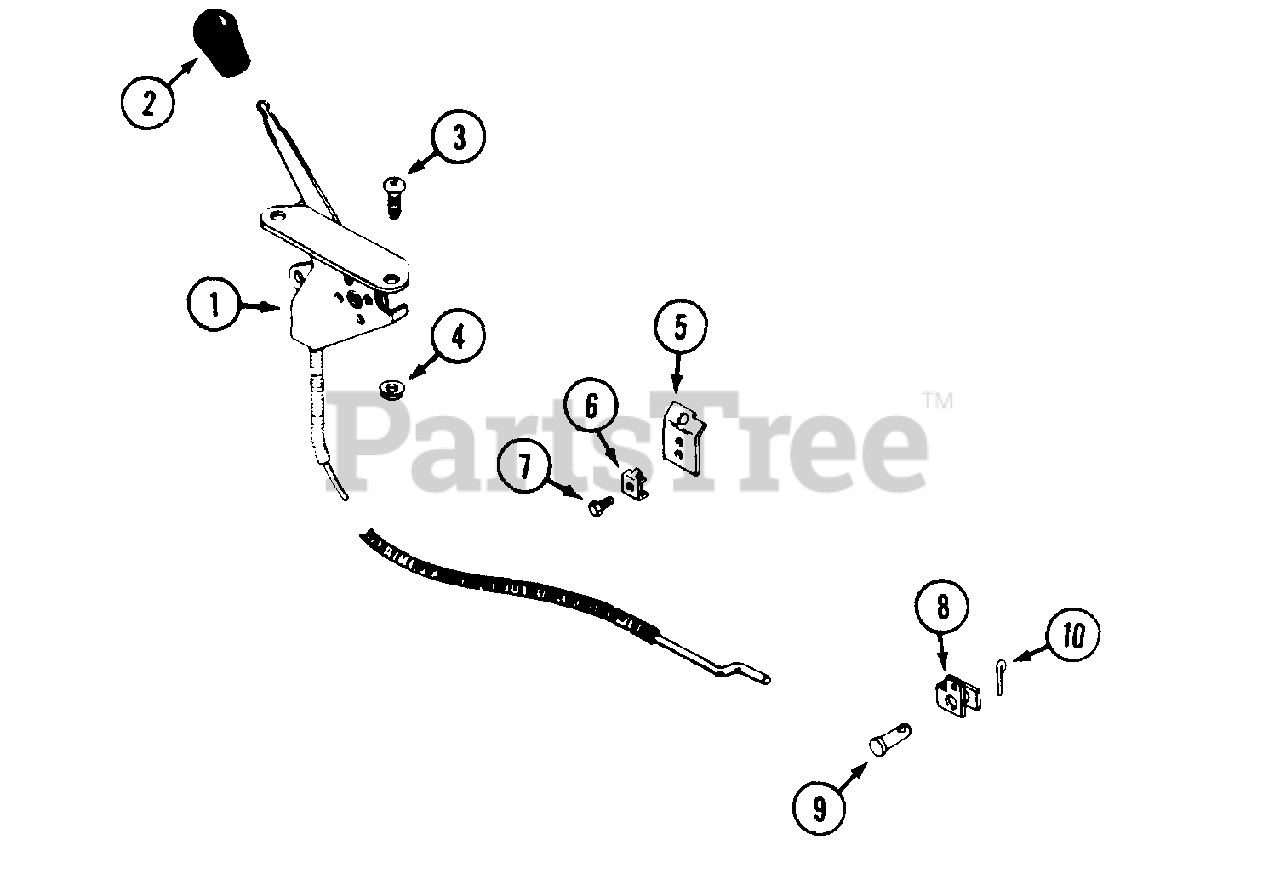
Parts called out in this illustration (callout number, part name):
1	THROTTLE
2	KNOB - throttle
3	SCREW - #10 - 24 x 3/4"
4	NUT - #10 - 24 flange lock
5	BRACKET - throttle
6	CLAMP - casing
7	SCREW - #10 - 24 x 3/4"
8	CLEVIS - extension
9	PIN - clevis 5/16" x 7/8"
10	PIN - cotter 3/32" x 3/4"
